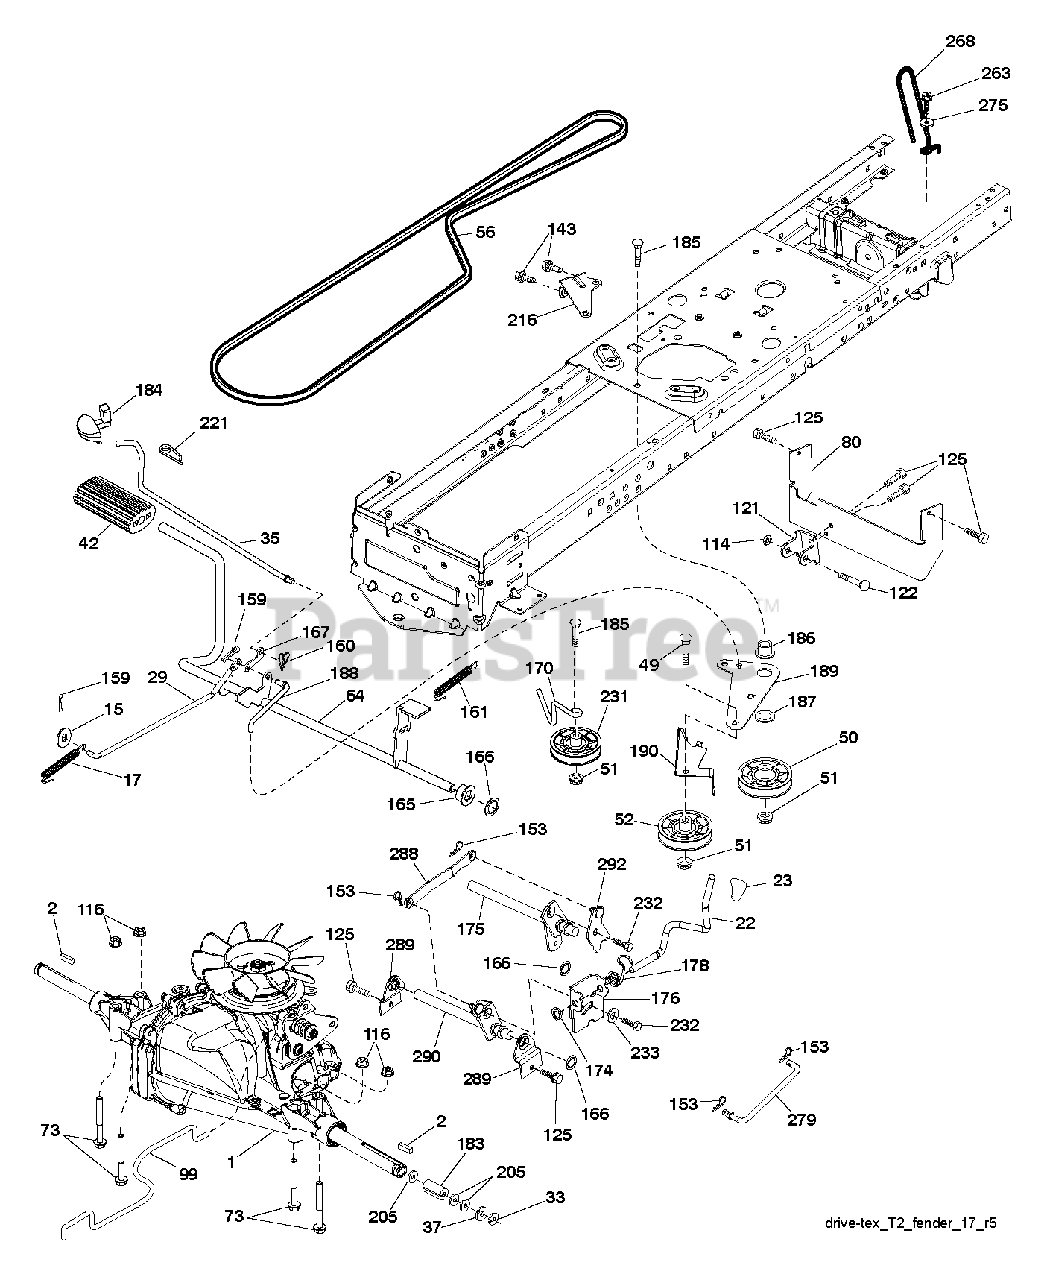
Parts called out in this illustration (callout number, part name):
17	SPRING.BRAKE.HG3000/3500
22	SHIFTER.ASM.HANDLE.SRD
23	KNOB.DUCKHEAD.1/2
35	ROD.BRAKE.PARKING.LT.T
42	PEDAL COVER T
49	BOLT
50	IDLER.FLAT.910.OFFSET
51	NUT LOCK FLG 3/8-16 UNC
52	IDLER.V-GROOVE.910.OFFSET
64	SHAFT.ASM.PEDAL.BRAKE.
73	BOLT HEX 5/16-18 GR 5
80	STRAP.TORQUE.FS.T2
99	ROD.ASM.BYPASS.SPRING.T2.FS
114	NUT.71038.31-18.HEX.NYLOCK
116	NUT LOCK HEX FLANGE 5/16-18
121	BRACKET STRAP TORQUE
122	BOLT.5/16-18X2.5
125	SCREW
153	RETAINER M
159	COTTER PIN
160	RETAINER CLIP
161	SPRING, RETURN LT
165	BUSHING.SHAFT.BRAKE.HAND
167	LATCH.BRAKE.SPRING
170	KEEPER.CENTER SPAN.1.688
174	NUT.PUSH.500.2006
175	SHAFT.ASM.SHFT.T2.TLT
176	ARM.CLEVIS.ROD.SHIFT
178	SPRING.TORSION.LIFT.HANDLE
183	SPACER, AXLE PVST
184	HANDLE.PARKING.BRAKE.LTTEX.667
186	SPACER.RETAINER
187	WASHER 12/32X2X10GA
188	LINK.CLUTCH.GROUND.DRIVE
189	BELLCRANK.GROUND.DRIVE.TEX.
190	KEEPER.BELLCRANK.DRIVE
216	BRACKET.PULLEY.IDLER.W/TEX
221	RETAINER.SPRING.CLIP.H
231	IDLER.V-GROOVE.1.688.OFFSET
232	BOLT FIN HEX 7/16-14 X 1
233	WASHER SERRATED
263	SCREW, 3/8-16X3/4
275	WASHER
279	LINK.SHIFT.T2
288	LINK.SHIFT.SLAVE.SRD
289	BRACKET.SUPPORT.SHIFT.OUTER
290	SHAFT.ASM.SHIFT.REAR.SRD
292	PLATE.ASM.SHIFT.FWD.SRD
